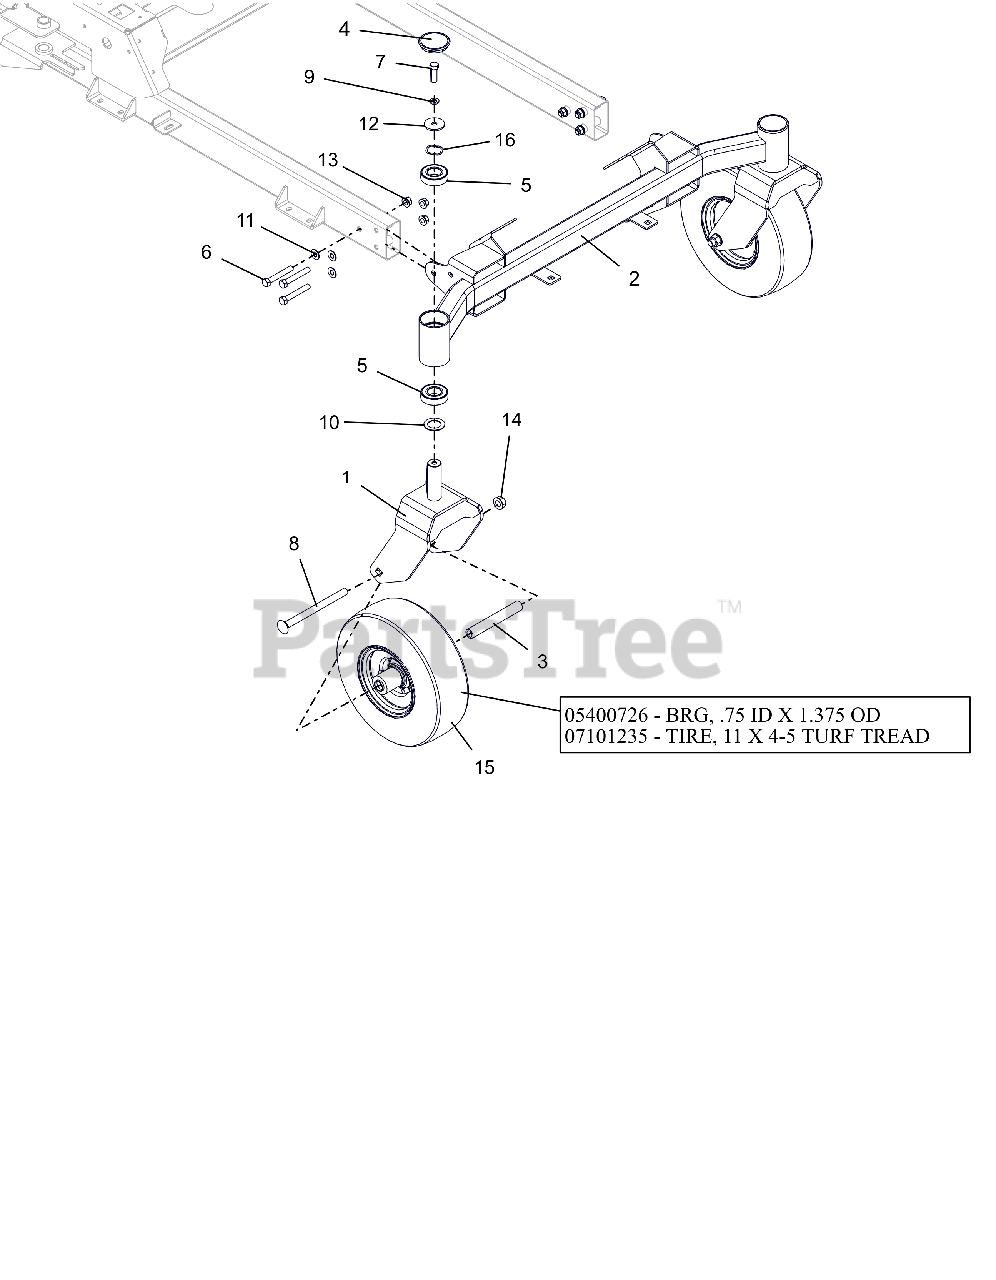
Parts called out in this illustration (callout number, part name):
1	WMT, CASTER FORK
2	WLDMT, AXLE FRONT
3	SPACER, ROLLED WHEEL
4	CAP, DUST
5	BRG,BALL 1.00X2.00X.563(1641)
6	BLT, HEX .38-16X2.50 G8 ZCC
7	BLT, HEX .38-16X1.25 G5 ZCC
8	BLT, RHSN .50-13X6.50 G5 ZCC
9	WSHR,LK-REG .375X.094 ZCC
10	WSHR-HRD-THRS 1.007X1.542X.062
11	WSHR,FLT-HRD.406X.812X.055 MZC
12	WSHR, FLT .380X1.50X.125 ZCC
13	NUT-LK-TOP-FLG .375-16 GG ZCC
14	NUT-LK-TOP-FLG .500-13 GF ZCC
15	ASM, WHL/TIRE 11X4.00-5
15	BRG, .75 ID X 1.375 OD
15	TIRE, 11X4-5 TURF TREAD
16	WSHR-WAVE 1.0X1.25X.028 .145FH
